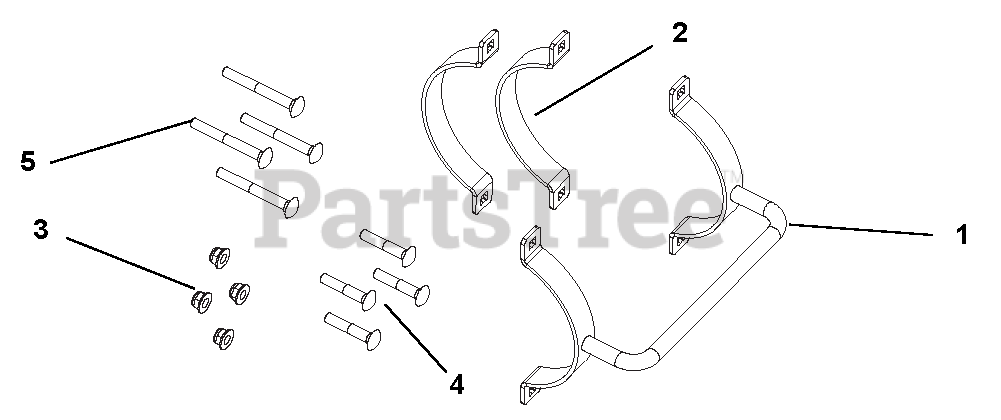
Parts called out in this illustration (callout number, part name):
1	WDMT, HYD. CYLINDER CLAMP
2	BRKT, CYLINDER CLAMP
3	@BLT-HEX .38-16X1.25 GR5 YWZC
4	BLT-RDHDSQNK .31-18X2.75 G5YZ
5	@BLT-RDHDSQNK .31-18X1.75 G5YZ
